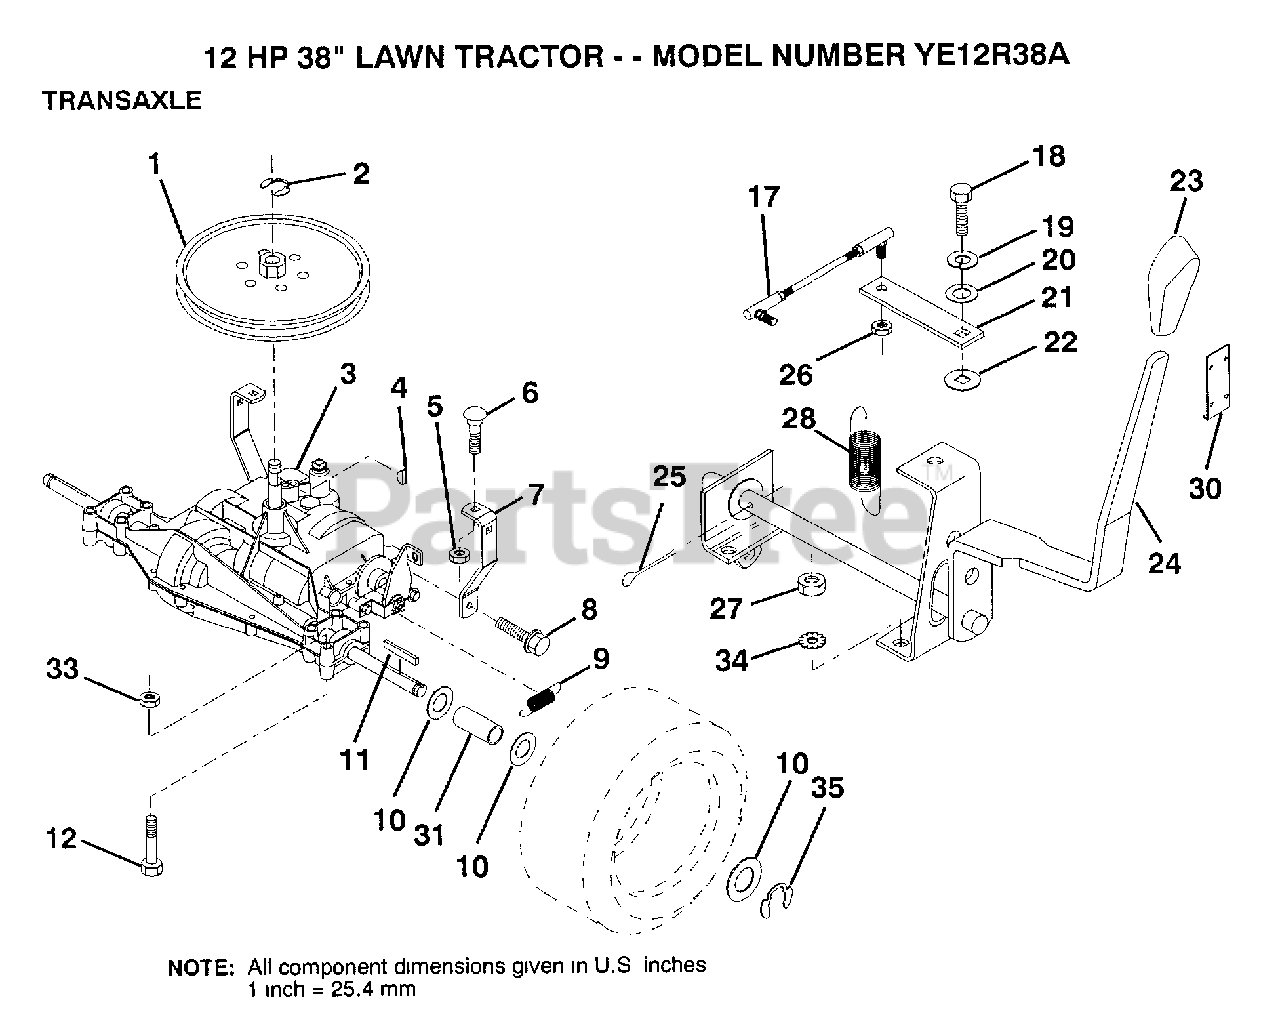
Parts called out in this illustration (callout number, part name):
1	PULLEY
6	BOLT
7	"STRAP,TORQUE"
8	SCREW
10	WASHER
11	SQUARE KEY
12	BOLT
17	"LINK,SHIFT"
19	LOCKWASHER
20	WASHER LT
21	"ARM,SHIFT"
22	WASH-SHFT PLT LT
23	"KNOB,SHT CONTROL"
25	PIN COTTER 1/8
26	NUT.LOCK.5/16-24
28	"SPRING,EXT"
30	KNOB RETAINER
31	SPACER
34	LOCKWASHER.5/16.E
35	E-RING LT
